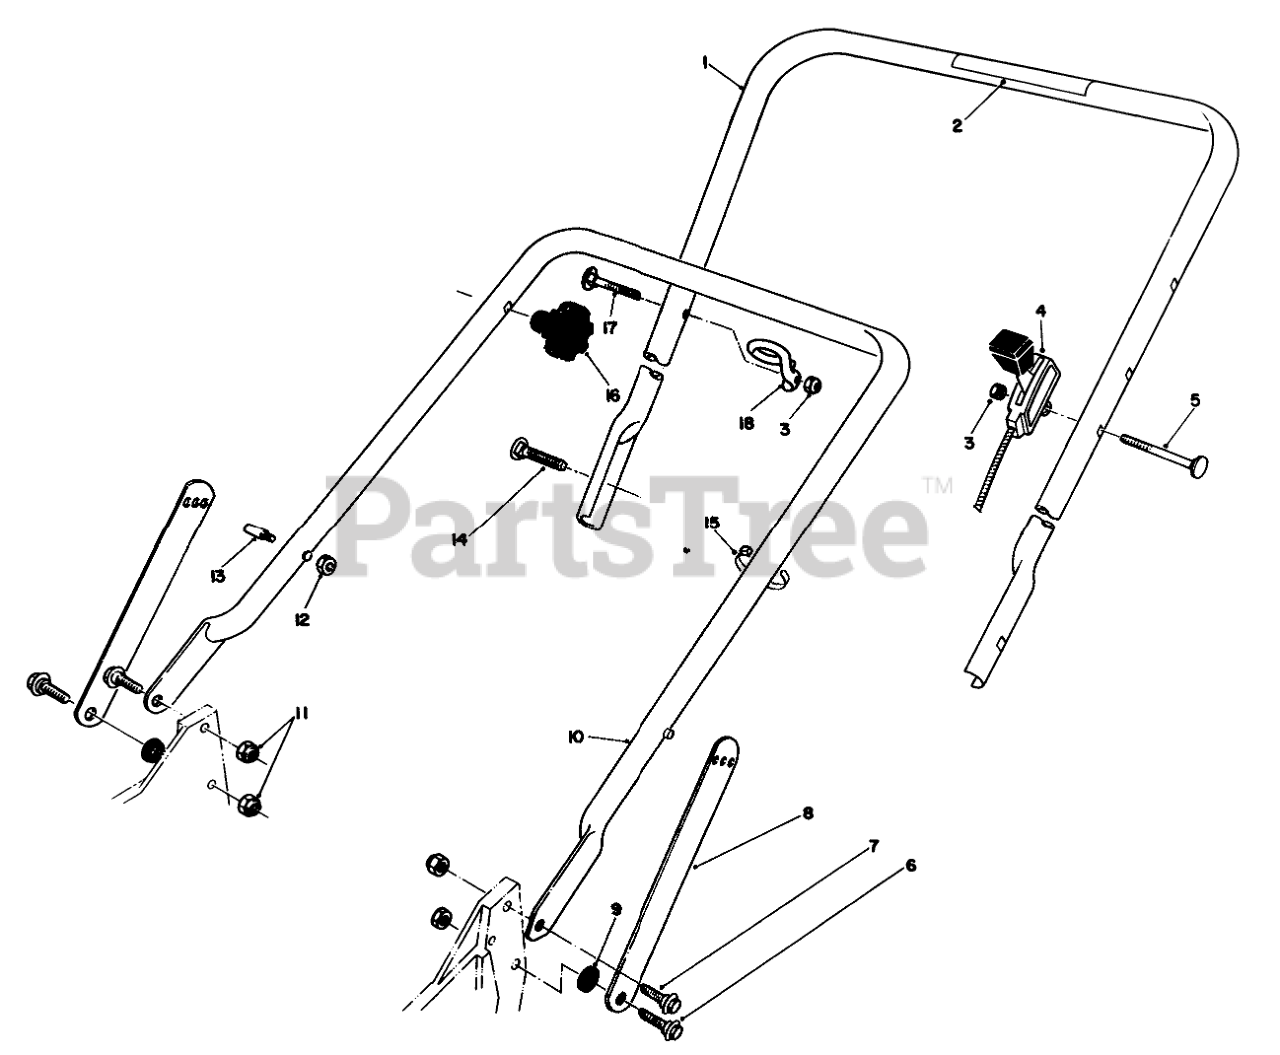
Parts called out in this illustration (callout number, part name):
1	Handle-Upper (Incl. Ref. #2)
2	WARNING DECAL
3	NUT-LOCK, NI
4	THROTTLE CONTROL
5	SCREW-HANDLE
6	SCREW-SHOULDER
7	SCREW-SHOULDER
8	Handle Latch
9	SPACER
10	LOWER HANDLE ASM
11	NUT-LOCK, NI
12	NUT-LOCK, NI
13	HANDLE PIN
14	5/16-18 X 2 HNDLE SCREW
15	TIE-CABLE
17	HANDLE SCREW
18	Guide
